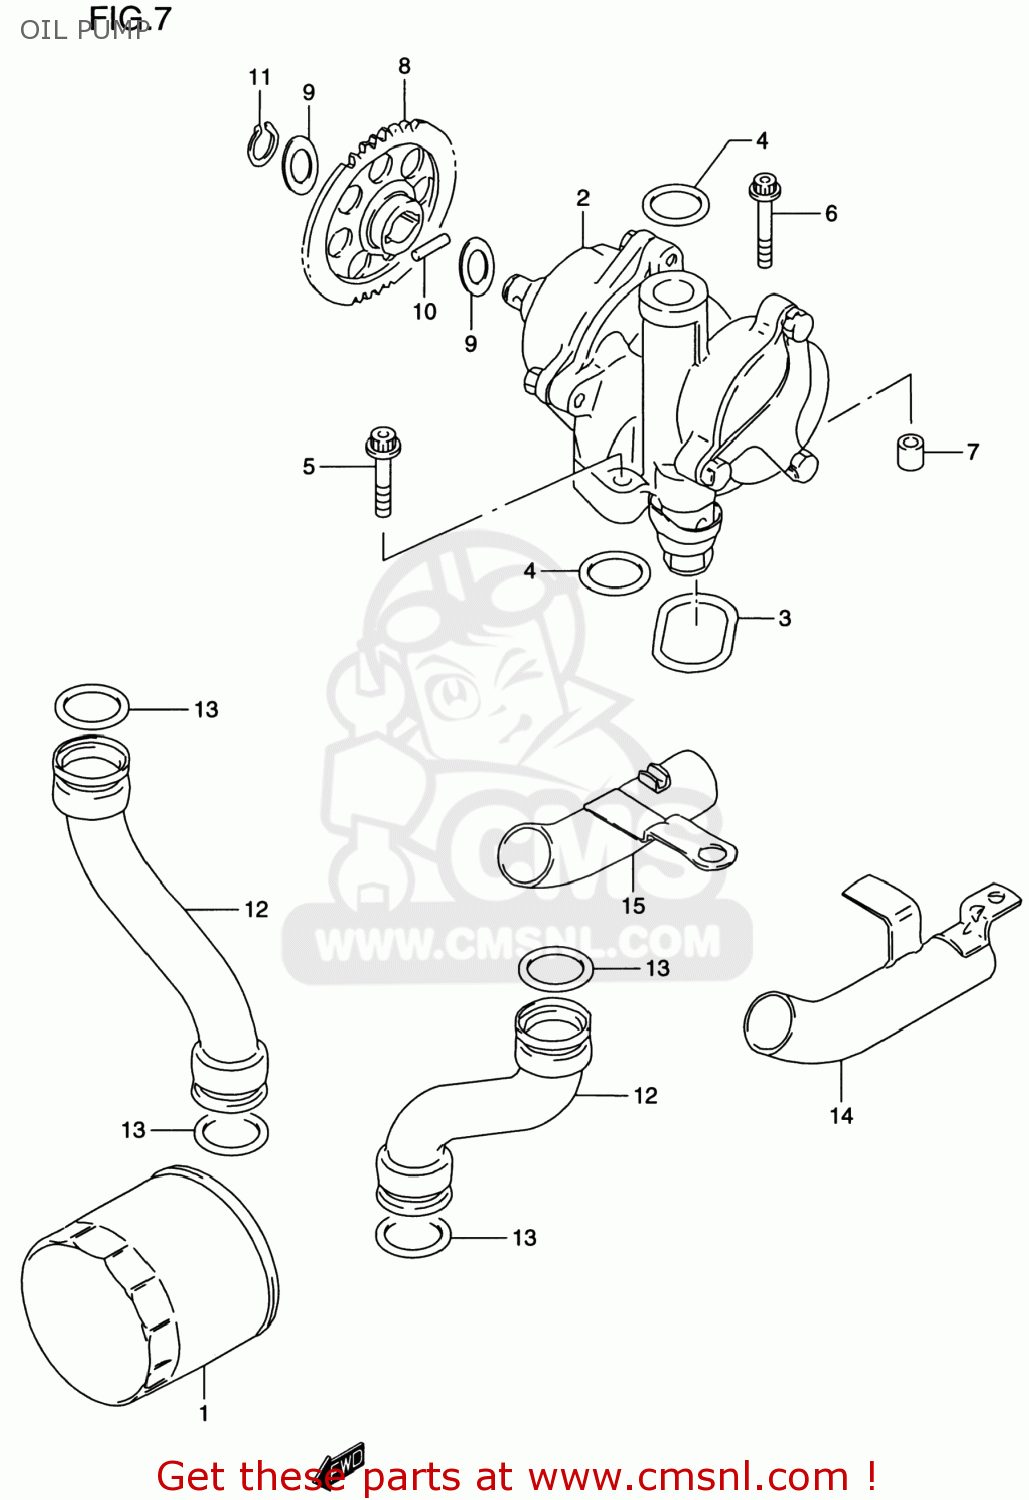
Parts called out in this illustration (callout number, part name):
1	FILTER ASSEMBLY,ENGINE OIL
2	PUMP ASSY,OIL
3	O RING,OIL PUMP
4	O RING(D:3.2,ID:17.8)
5	BOLT
6	BOLT
7	PIN
8	GEAR,OIL PUMP DRIVEN(NT:37)
9	SHIM
10	PIN(5X18)
11	CIRCLIP,12 MM
12	PIPE,OIL OUTLET
13	O RING(D:3.7,ID:21.7)
14	PIPE,OIL OUTLET UNDER,L
15	PIPE,OIL OUTLET UNDER,R
